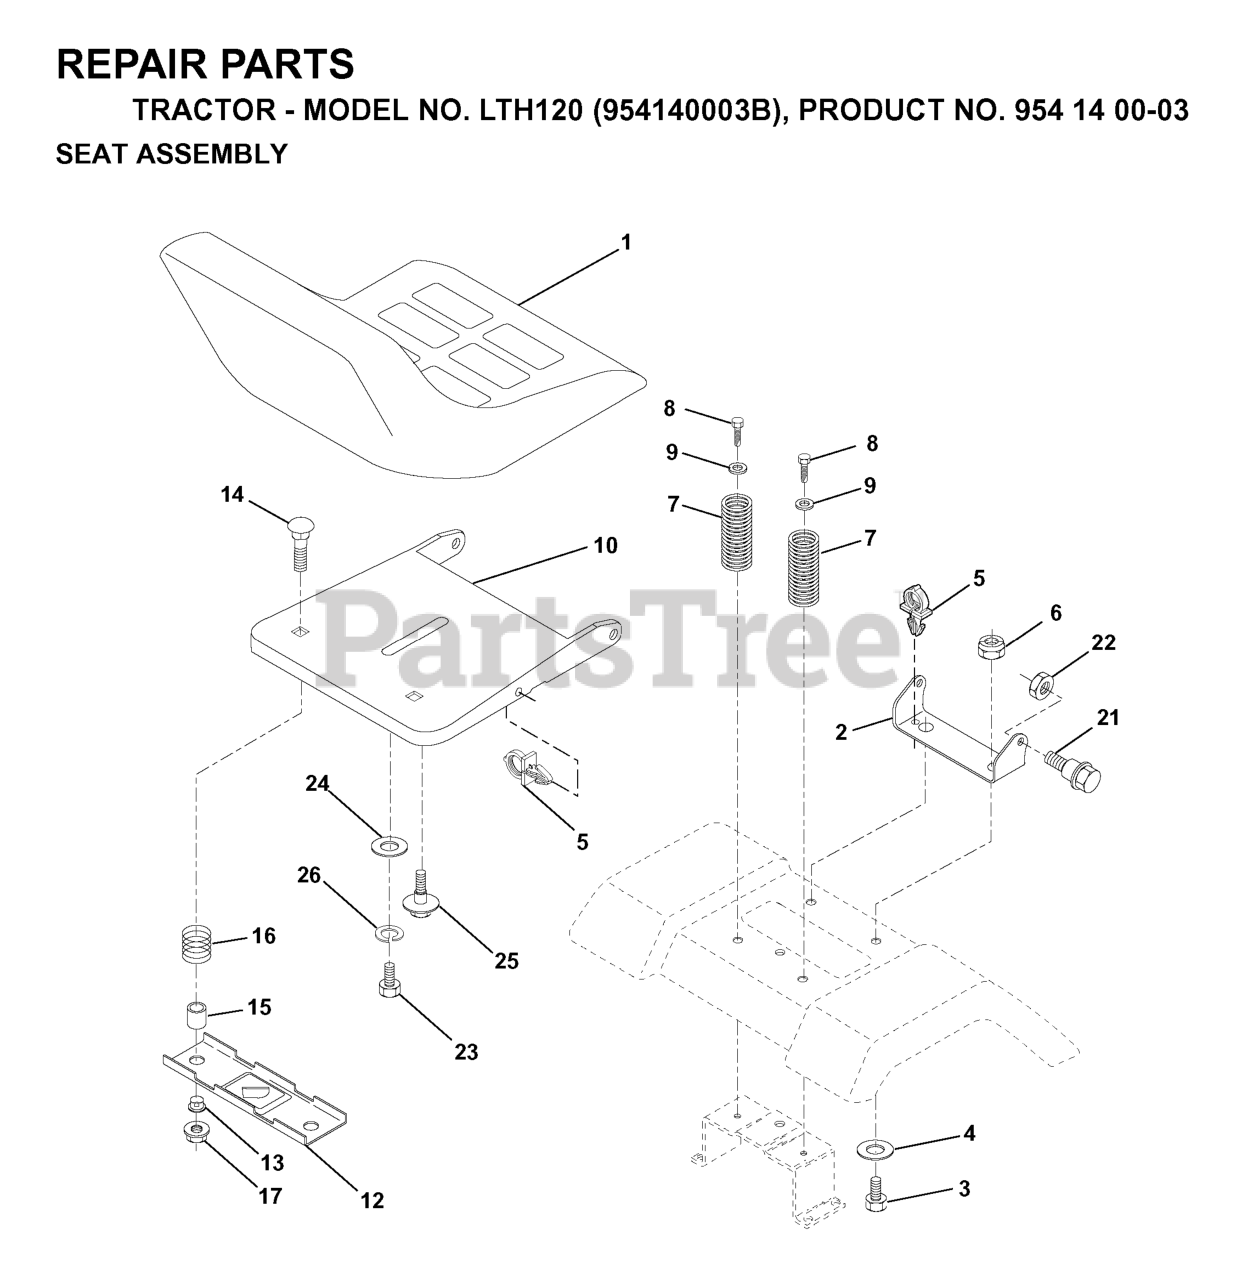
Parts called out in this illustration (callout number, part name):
1	SEAT
2	SEAT PIVOT BRKT
3	BOLT
6	NUT
7	SPRING COMPRESSION
8	SCREW GTV
9	WASHER
10	PAN, SEAT
12	BRKT SWITCH
14	BOLT.ROUND.HEAD.SQUARE.NECK
15	SPACER SPLIT 28X.96
17	NUT T
21	BOLT SHOULDER 5/16-18
22	NUT.71038.31-18.HEX.NYLOCK
23	BOLT
25	BOLT,SHOULD
26	LOCKWASHER
